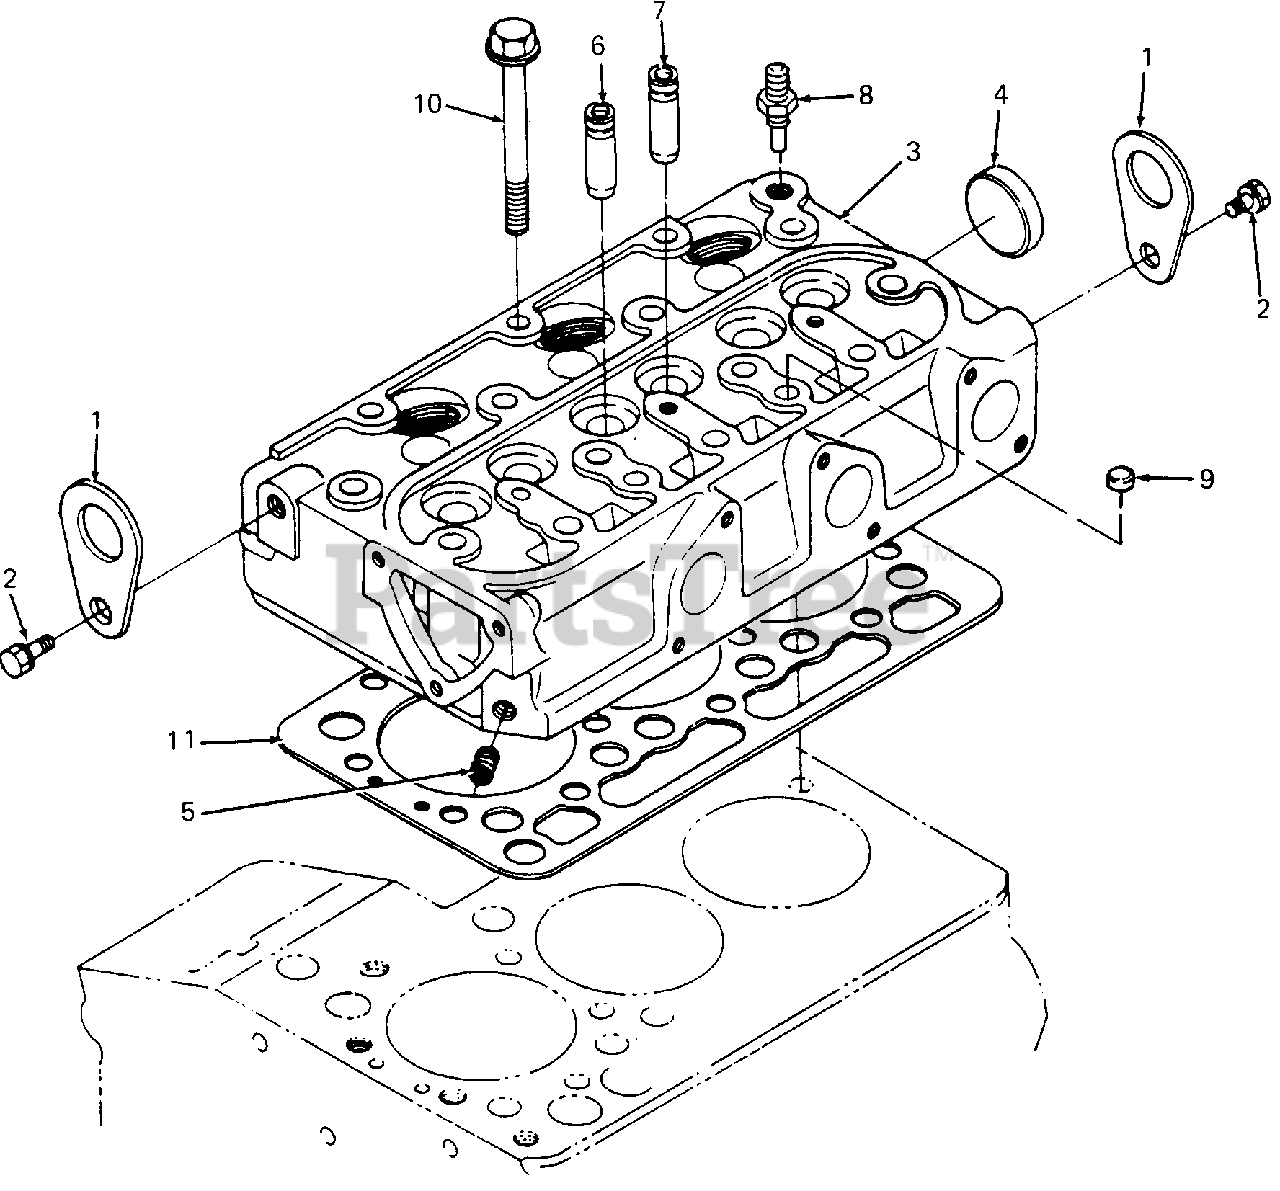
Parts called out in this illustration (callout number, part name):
2	Screw, Hex Cap
3	Head Assy, Cylinder
6	Guide, Intake Valve
7	Guide, Exhaust Valve
8	Switch, Temperature
11	Gasket, Head
